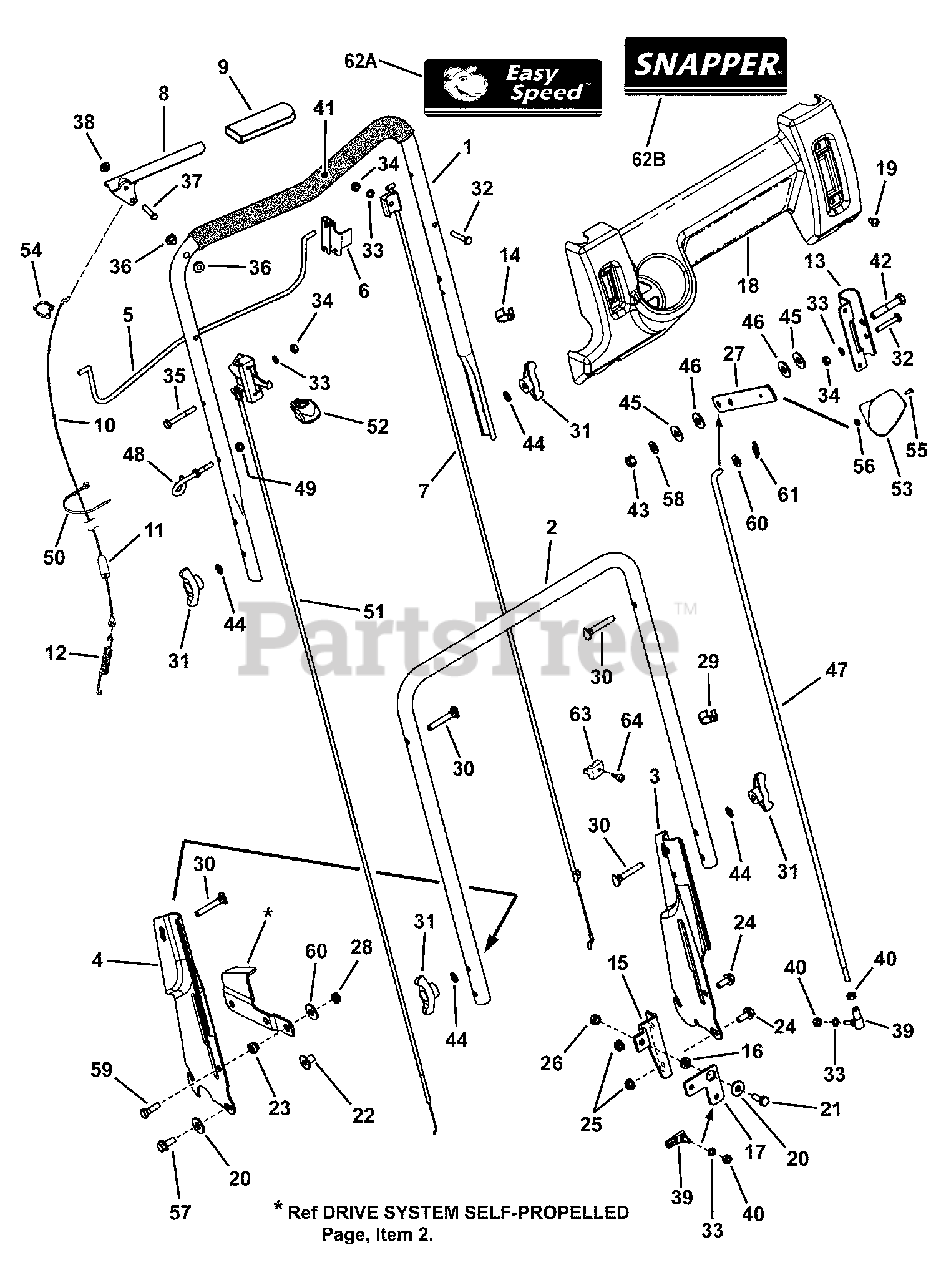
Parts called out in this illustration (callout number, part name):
1	HANDLE, Upper
2	HANDLE, Middle
3	HANDLE, Lower LH (Adjustable)
4	HANDLE, Lower RH (Adjustable)
5	BAIL, OPC Control
6	CLIP, Zone Control
7	* CABLE, Zone Control (52-63/64" Long)
7	* CABLE, Zone Control (53-47/64" Long)
8	HANDLE, Clutch
9	GRIP, International Symbol
10	CABLE, Clutch Control (41-1/4" Long)
11	COVER, Vinyl
12	SPRING, Clutch- 21S
13	BRACKET, Shift
14	TIE, Wire, 1.29 long, black
15	BRACKET, Bell Crank
16	SPACER, .33 x .63 x .156
17	BELL CRANK
18	CONTROL PANEL (w/o Electrical Switch Hole)
18	CONTROL PANEL (w/o wheel drive slot)
19	SCREW, 1/4-20 x 1/2" Pan Head Self-Tap (Torx)
20	WASHER, .33 x .88 x .09 Flat
21	SCREW, 5/16-18 x 7/8" Hex Head Cap, GR 5
22	TEENUT, 5/16-18
23	BUSHING, Differential, .328 x .625 x .41
24	BOLT, 5/16-18 x 3/4" Hex Flange Lock GR 5
25	NUT, 5/16-18 Hex Flange Lock, GR 5
26	NUT, 5/16-18 Hex Center Lock
27	LEVER, Shift
28	NUT, 5/16-24 Hex Center Lock GR 5
29	CLIP, Wiring Harness
30	SCREW, 5/16-18 x 1-7/8" Curved Head GR 2
31	KNOB, 5/16-18 Wing (Black)
32	SCREW, 1/4-20 x 1-1/2" Hex Head Cap GR 5
33	WASHER, 1/4" Internal Tooth Lock
34	NUT, 1/4-20 Hex
35	SCREW, 1/4-20 x 2" Hex Head Cap, GR 5
36	BUSHING, .27 x .35 x .4 Flange
37	PIN, 1/4 x 1-1/2"
38	PUSH-NUT, 1/4"
39	BALL JOINT, 1/4-28
40	NUT, 1/4-28 Hex
41	FOAM GRIP, 18.75" long
42	SCREW, 3/8-16 x 2" Hex Head Cap, GR 5
43	NUT, 3/8-16 Hex Center Lock
44	WASHER, 5/16" Internal Tooth Lock
45	WASHER, 7/16" Flat
46	WASHER, Nylon
47	ROD, Speed Control (1/4-28 thread)
48	GUIDE, Rope (1/4-20 thread)
49	NUT, 1/4-28 Hex GR 5 or B
50	CABLE-TIE, 7"
51	THROTTLE CONTROL, .48 x .61
51	THROTTLE CONTROL, RP, D.O.V. Engine
52	THROTTLE KNOB
53	KNOB, Shift
54	CLAMP, 7/8" Double Cable
55	SCREW, #8-32 x 1/2" Cross Recess Filister Head Machine
56	NUT, #8-32 Hex
57	SCREW, 5/16-18 x 1-1/4" Hex Washer Head Self-Tap
58	WASHER, Belleville
59	SCREW, 5/16-24 x 1" Hex Head Cap GR 5
60	WASHER, 11/32" Flat
61	COTTER PIN, 5/16 Self Lock
62A	DECAL, Easy Speed, Control Panel
62B	DECAL, Snapper Control Panel
63	CLAMP, Casing
64	SCREW, #10-32 x 5/8" Self-Tap
